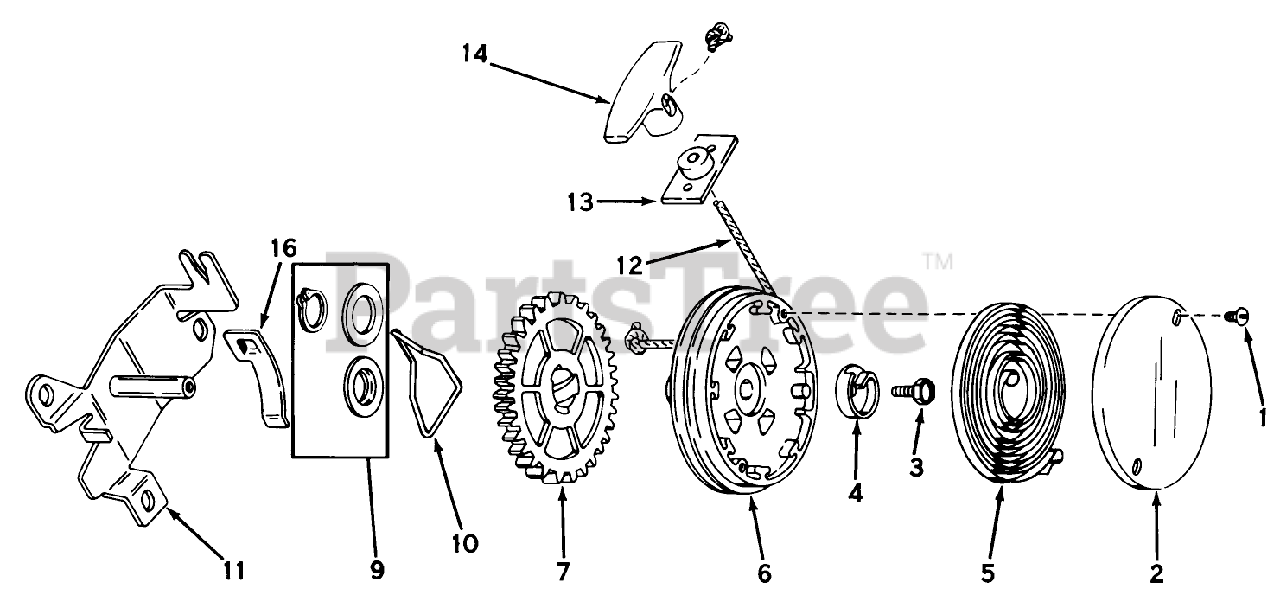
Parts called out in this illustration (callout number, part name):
1	Screw, Cover
2	Cover, Spring
4	Hub Spring
5	Spring, Rewind
6	Pulley Assy. (Incl. No. 9)
7	Gear
9	Kit, Thrust Wash. & Snap Rg.
11	Bracket Assy. Mounting
12	Rope, Starter
13	Bracket Assy.
14	Handle-Starter
16	Clip Rope
